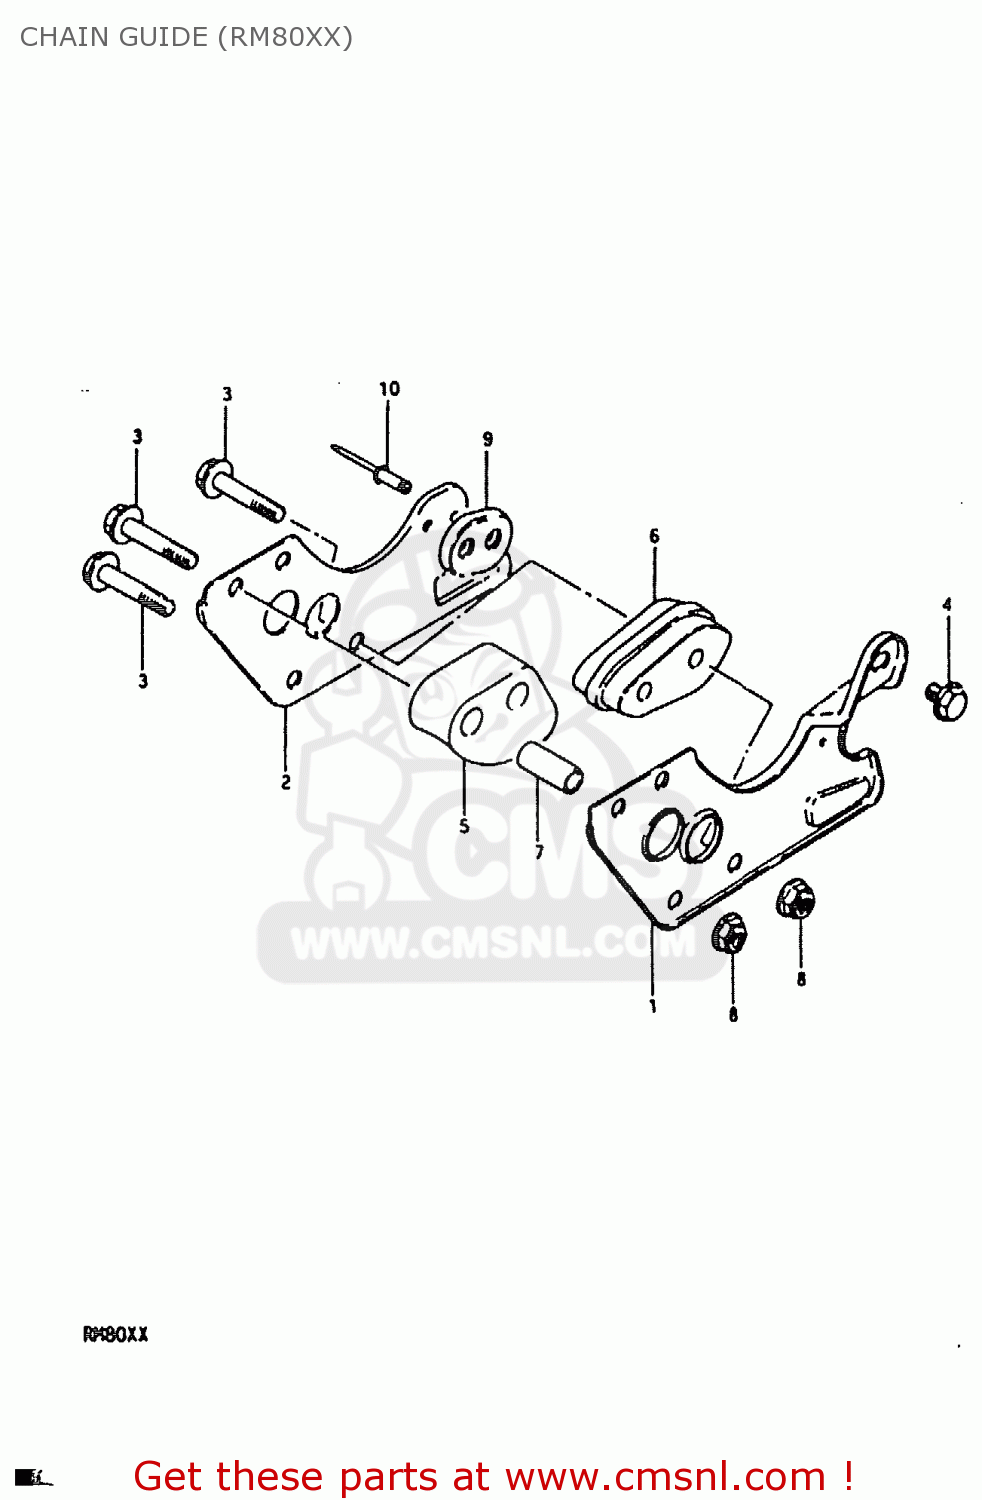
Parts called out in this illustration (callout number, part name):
1	GUIDE,CHAIN,OUTER
2	GUIDE,CHAIN,INNER
3	BOLT 6X35
4	BOLT
5	ROLLER,CHAIN GUIDE
6	DEFENSE,CHAIN GUIDE
7	SPACER(6.8X10X24.2)
8	NUT
9	PAD,DRIVE CHAIN GUIDE
10	RIVET
